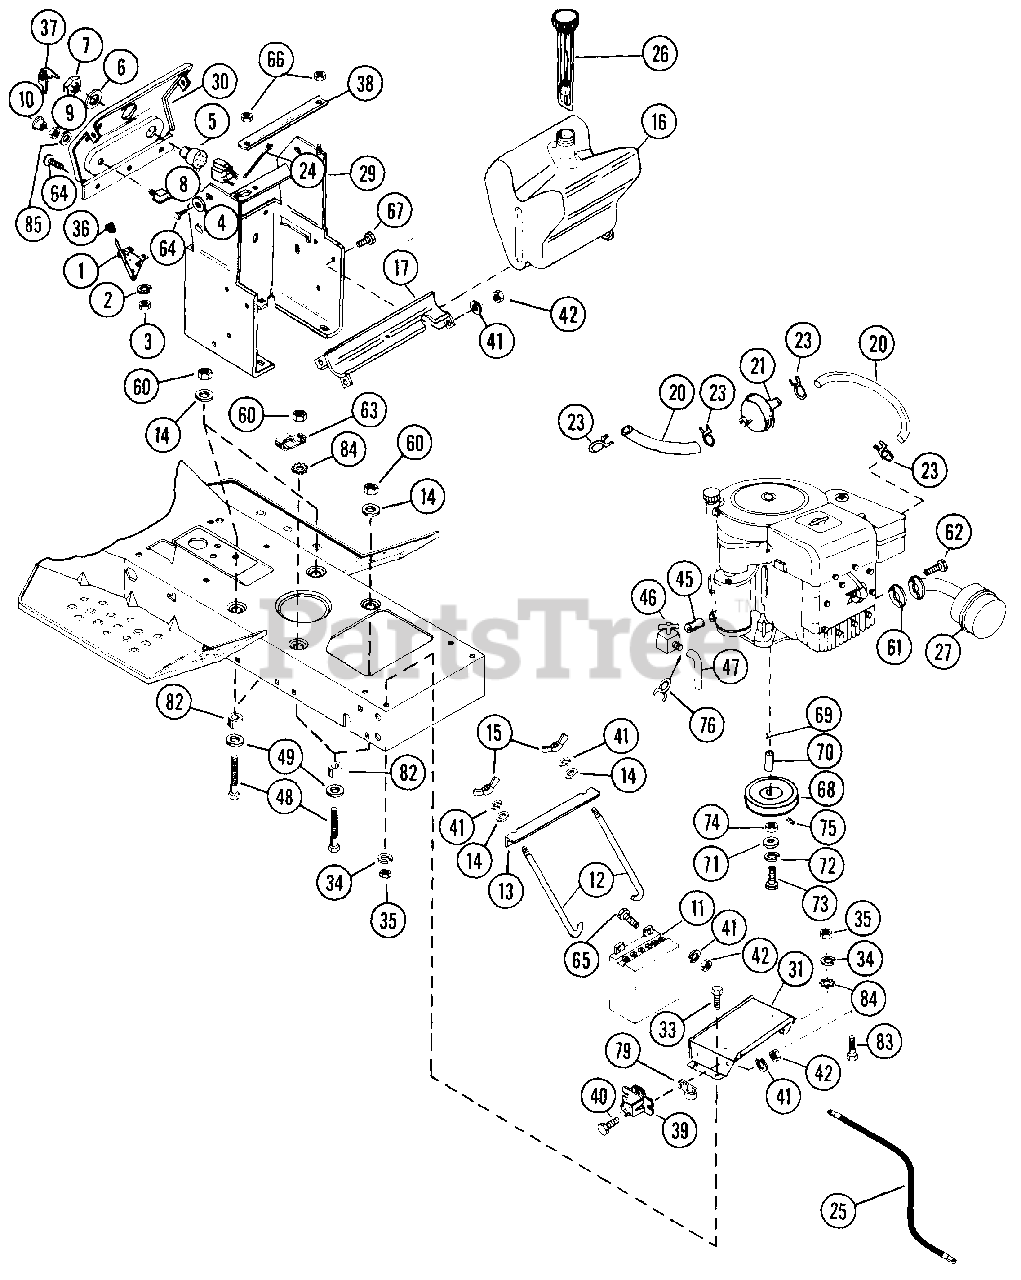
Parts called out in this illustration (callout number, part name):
1	THROTTLE CONTROL
2	WASHER, LOCK NO. 10 SP.
3	NUT
4	WASHER, FLAT .250X.500X.049
5	IGNITION SWITCH
6	WASHER, LOCK INT. TOOTH
7	NUT, JAM 9/16-24
8	LIGHT SWITCH
9	NUT, HEX 1/2-20
10	KNOB
11	BATTERY, 12 VOLT SMALL
12	HOOK BOLT
13	BATTERY HOLD DOWN
14	WASHER, FLAT .312X.734X.065
15	NUT, WING 1/4-20
16	FUEL TANK
17	LOWER TANK SUPPORT
20	HOSE
21	FUEL FILTER
23	HOSE CLAMP
24	TIE DOWN
25	CABLE, BATTERY TO ENGINE BASE
26	FUEL GAUGE
27	EXHAUST MUFFLER
29	DASH BASE
30	DASH
31	BATTERY STAND
33	BOLT, HEX 5/16-18X.625
34	WASHER, LOCK 3/8 SP HEAVY
35	NUT, HEX 5/16-18
36	KNOB
37	KEY, IGNITION SWITCH
38	CLAMP, STRAP
39	SOLENOID
40	BOLT, HEX 1/4-20X1.00
41	WASHER, LOCK 1/4 REG.
42	NUT, HEX 1/4-20
45	BUSHING
46	DRAIN LOCK
47	TUBE
48	BOLT, HEX 5/16-18X2.00
49	WASHER, 5/16X1-5/8X.135
60	NUT, LOCK 5/16-18
61	GASKET
62	BOLT, HEX 5/16-18X.75
63	J-CLAMP
64	TAPPING SCREW, 10-16X3/8
65	BOLT, HEX 1/4-20X.875
66	NUT, LOCK 1/4-20
67	BOLT, HEX 1/4-20X.50
68	SHEAVE, ENGINE
69	KEY, STRAIGHT 1/4X1/4X1
70	BEARING SPACER
71	WASHER, FLAT .500X1.250X.083
72	WASHER, LOCK SP HEAVY
73	BOLT, HEX 7/16-20X1
74	SPACER
75	SETSCREW, 5/16-18 UNC-3AX1/4
76	HOSE CLAMP
79	CLIP
82	ENGINE SPACER
83	BOLT, HEX 5/16-18X1.00
84	WASHER, LOCK 5/16 EXT TH TYA
85	WASHER
